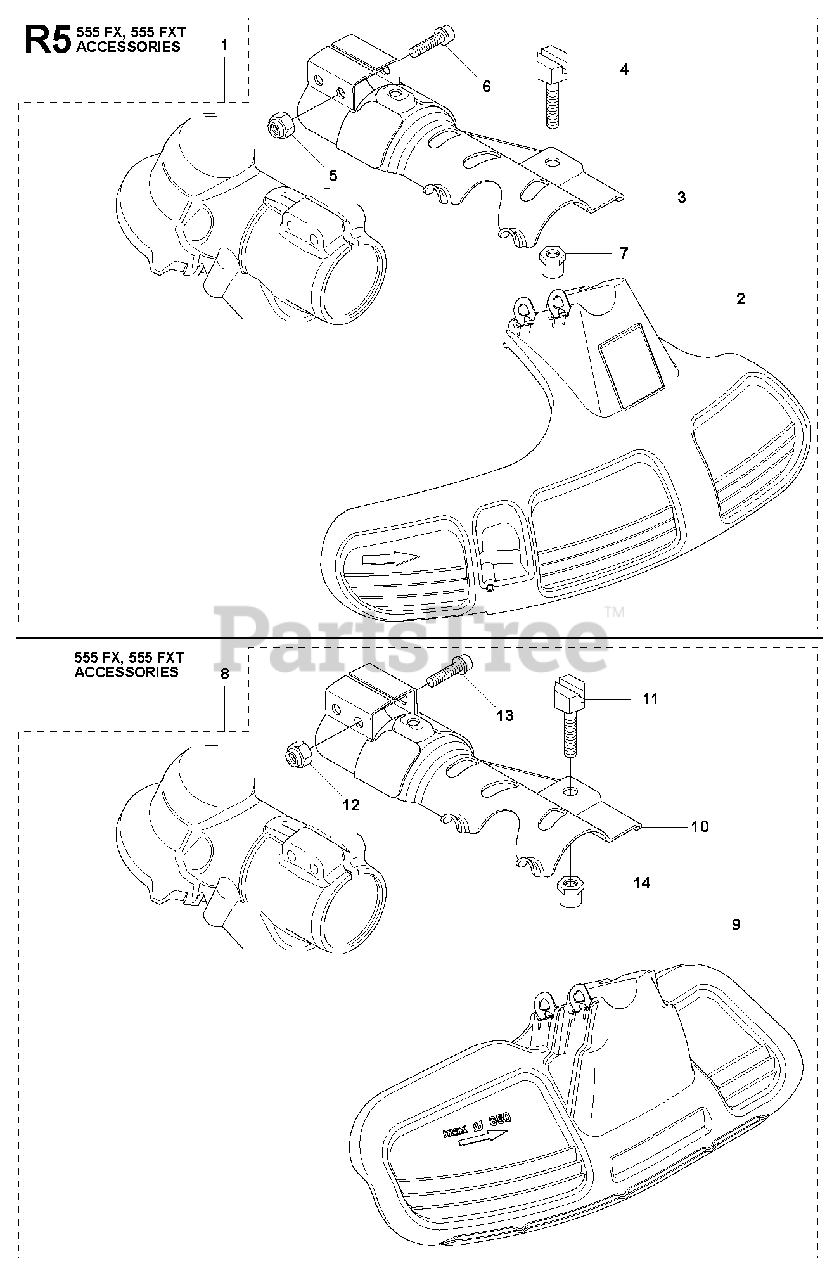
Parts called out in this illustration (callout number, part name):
1	GUARD ASSY
2	PROTECTION
3	ATTACHMENT PLATE
4	SCREW
5	LOCKNUT M6
6	SCREW
7	SPACING SLEEVE
8	METAL GUARD
9	BLADE GUARD GRASS
10	ATTACHMENT PLATE
11	SCREW
12	LOCKNUT M6
13	SCREW
14	SPACING SLEEVE
